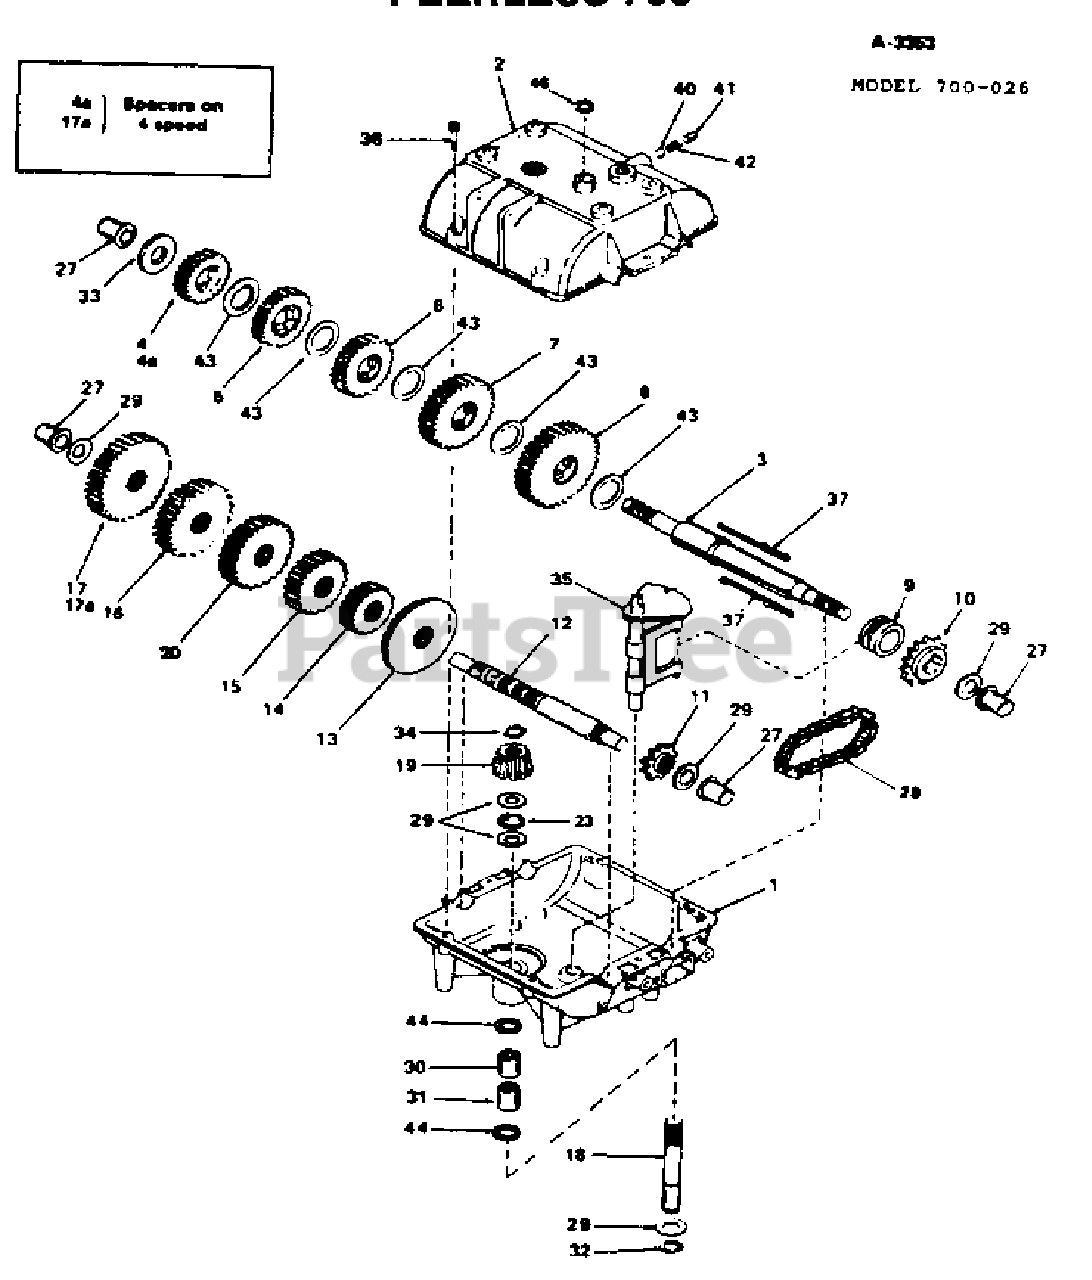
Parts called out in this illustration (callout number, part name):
1	CASE, TRANSMISSION
2	COVER, TRANSMISSION
3	SHAFT, OUTPUT & BRAKE
5	GEAR, SPUR(30 TEETH)
7	GEAR, SPUR(35 TEETH)
8	GEAR, SPUR(37 TEETH)
9	COLLAR, SHIFT
10	SPROCKET(18 TEETH)
11	SPROCKET(9 TEETH)
12	SHAFT, COUNTER
13	GEAR, BEVEL(42 TEETH)
14	GEAR, SPUR(12 TEETH)
15	GEAR, SPUR(15 TEETH)
16	GEAR, SPUR(20 TEETH)
18	SHAFT, INPUT
19	BEVEL PINION, INPUT
20	GEAR, SPUR(18 TEETH)
23	BEARING, THRUST
27	BUSHING, FLANGED
28	CHAIN, ROLLER(NO.41 CHAIN, 24 LINKS)
29	WASHER, THRUST
30	BEARING, NEEDLE
31	BEARING, NEEDLE
32	RING, RETAINING
33	WASHER, THRUST
34	RING, RETAINING
35	ROD & FORK ASSY., SHIFT
36	SCREW, FLANGED HEX HD. TF, 1/4-20 X 1-1/4
40	BALL, STEEL, 5/16"
41	SCREW, SET 3/8-16 X 3/8
42	SPRING
43	WASHER, THRUST
44	"O" RING
46	SEAL, SQUARE CUT
